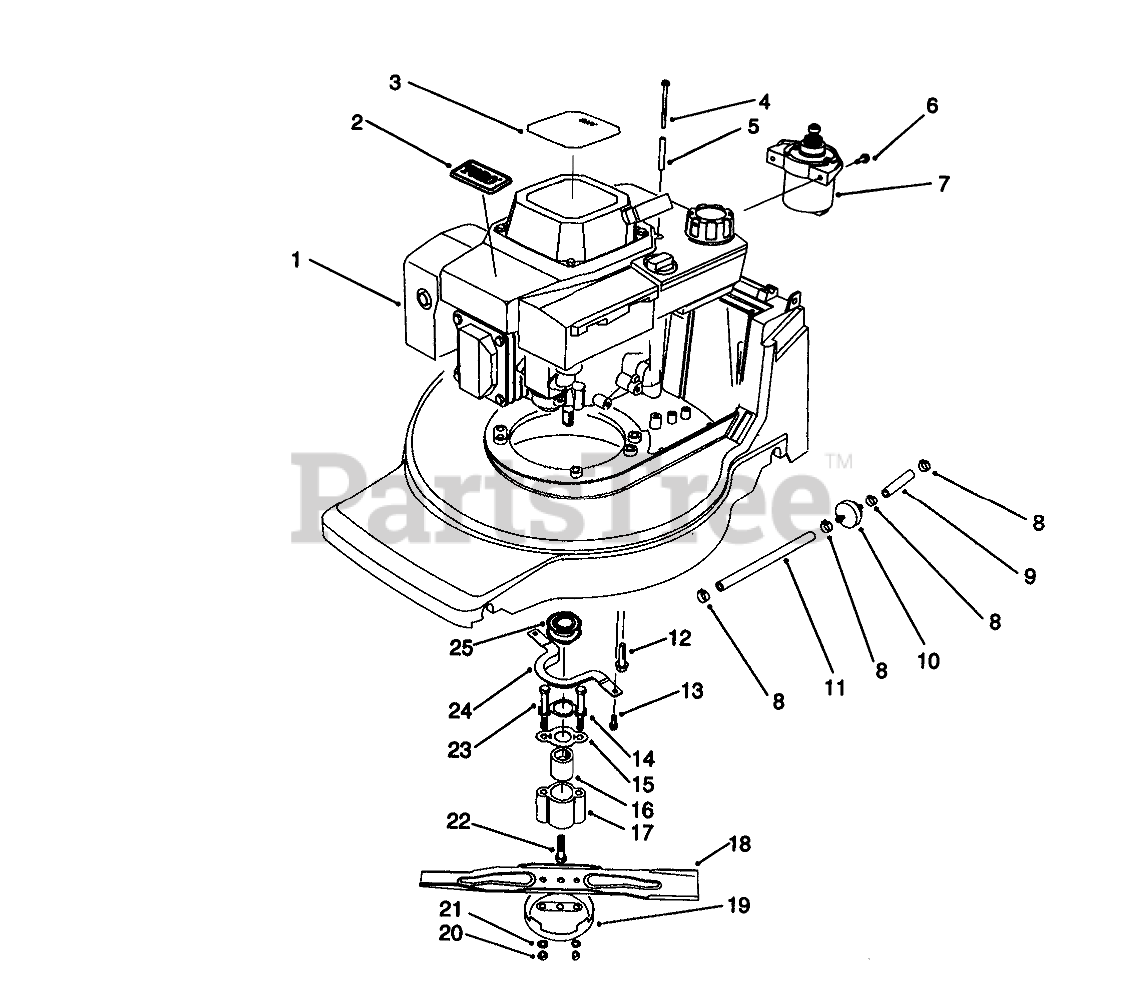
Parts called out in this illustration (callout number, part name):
1	ENGINE ASSY OHV BBC/K
2	TORO LOGO PLT
3	DECAL-HV INT'L
4	THRD FORMING SCREW
5	TUBULAR SPACER
6	SCREW
7	STARTER MOTOR ASM
8	CLAMP-FUEL LINE
9	LINE-GAS
10	FILTER-FUEL
11	HOSE-FUEL
12	SCREW-HWHTF
13	SCREW-HWH
14	BLADE RETAINER BRKT
15	SPRING FRICTION
17	RETAINER
18	Blade-48cm
19	CUP-SCALP, ANTI
20	NUT-LOCK
21	WASHER
22	SCREW - CRANKSHAFT
23	SCREW - BLADE
24	Guide-Belt
25	PULLEY-DRIVE, ZONE START
